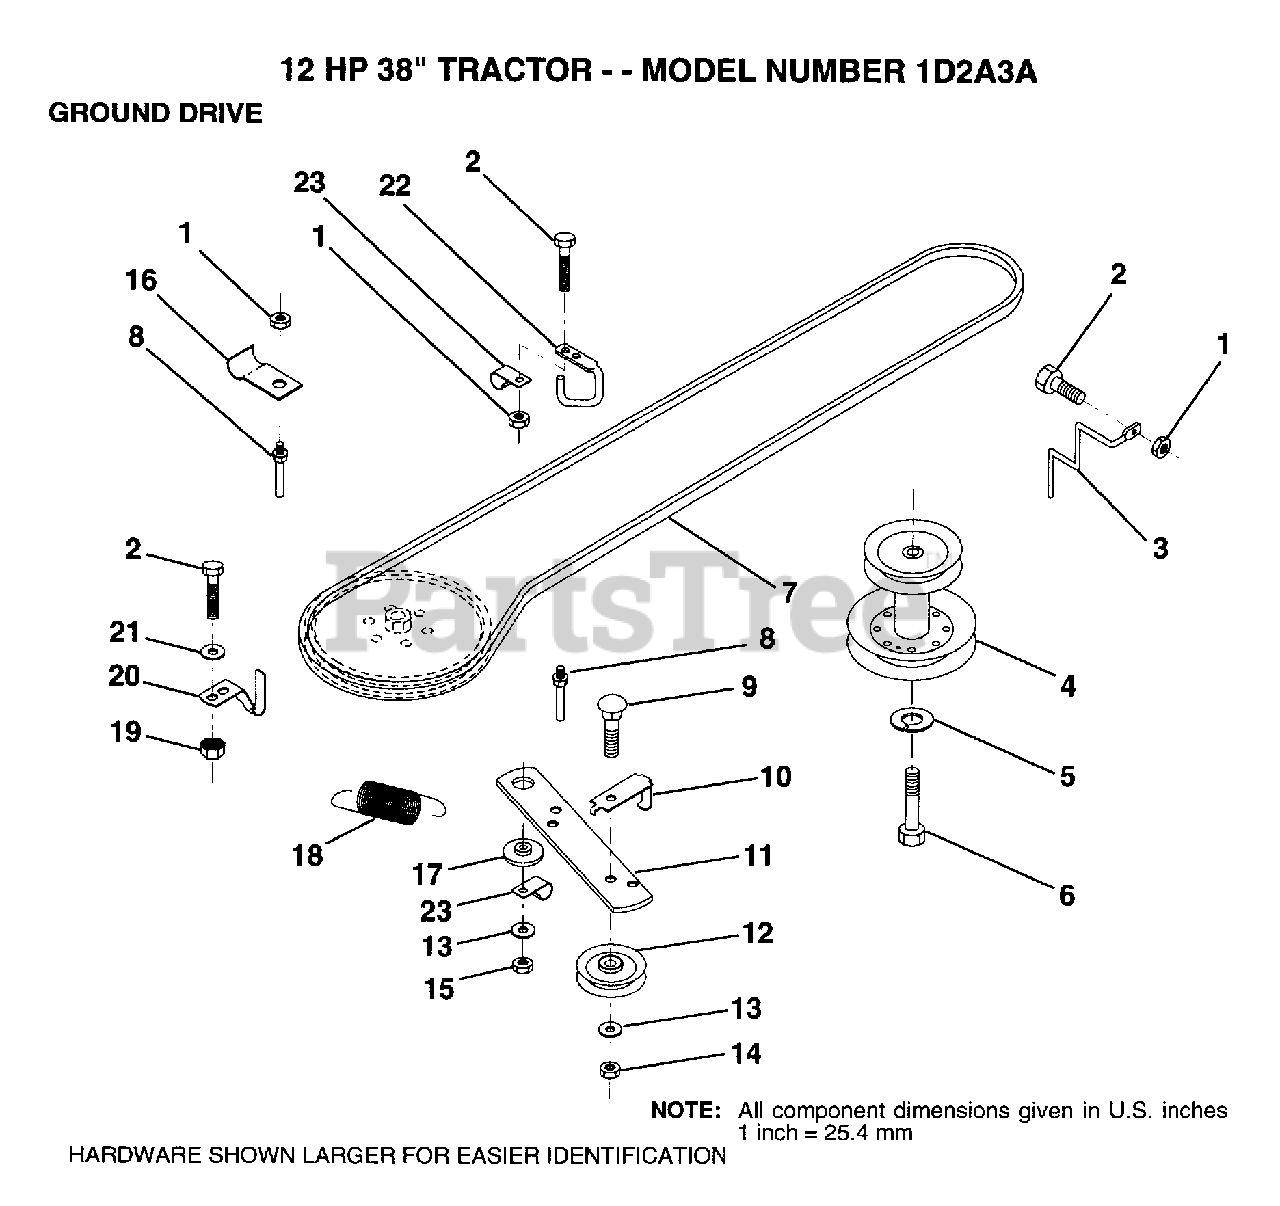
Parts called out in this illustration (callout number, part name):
2	BOLT
3	KEEPER MWR DR BLT
5	LOCKWASHER
6	BOLT
7	BELT
8	"KEEPER,DRIVE BELT"
9	BOLT
10	"KEEP,IDLER DR BEL"
13	WASHER
14	LOCKNUT
16	"CLIP,INSULATOR"
17	SPACER RETAINER
20	"KEEPER,DR BELT "
21	WASHER
22	"KEEPER,FRA DR BEL"
23	CLIP INSULATOR
